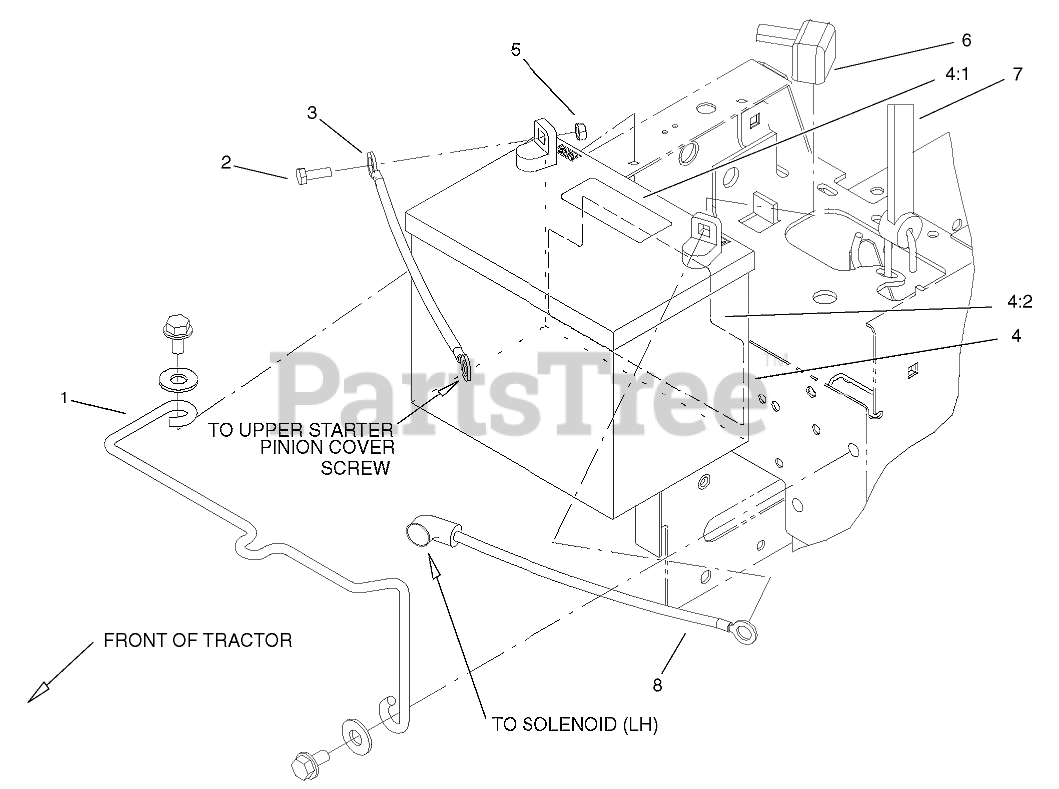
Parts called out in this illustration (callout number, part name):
1	ROD-BATTERY
2	SCREW-HH
3	CABLE-NEGATIVE, BLACK
4	BATTERY
4:1	Decal-Battery
4:2	Decal-Battery
5	NUT-LOCK, NI
6	BOOT-TERMINAL
7	HOLDDOWN-BATTERY
8	CABLE-BATTERY, POSITIVE
